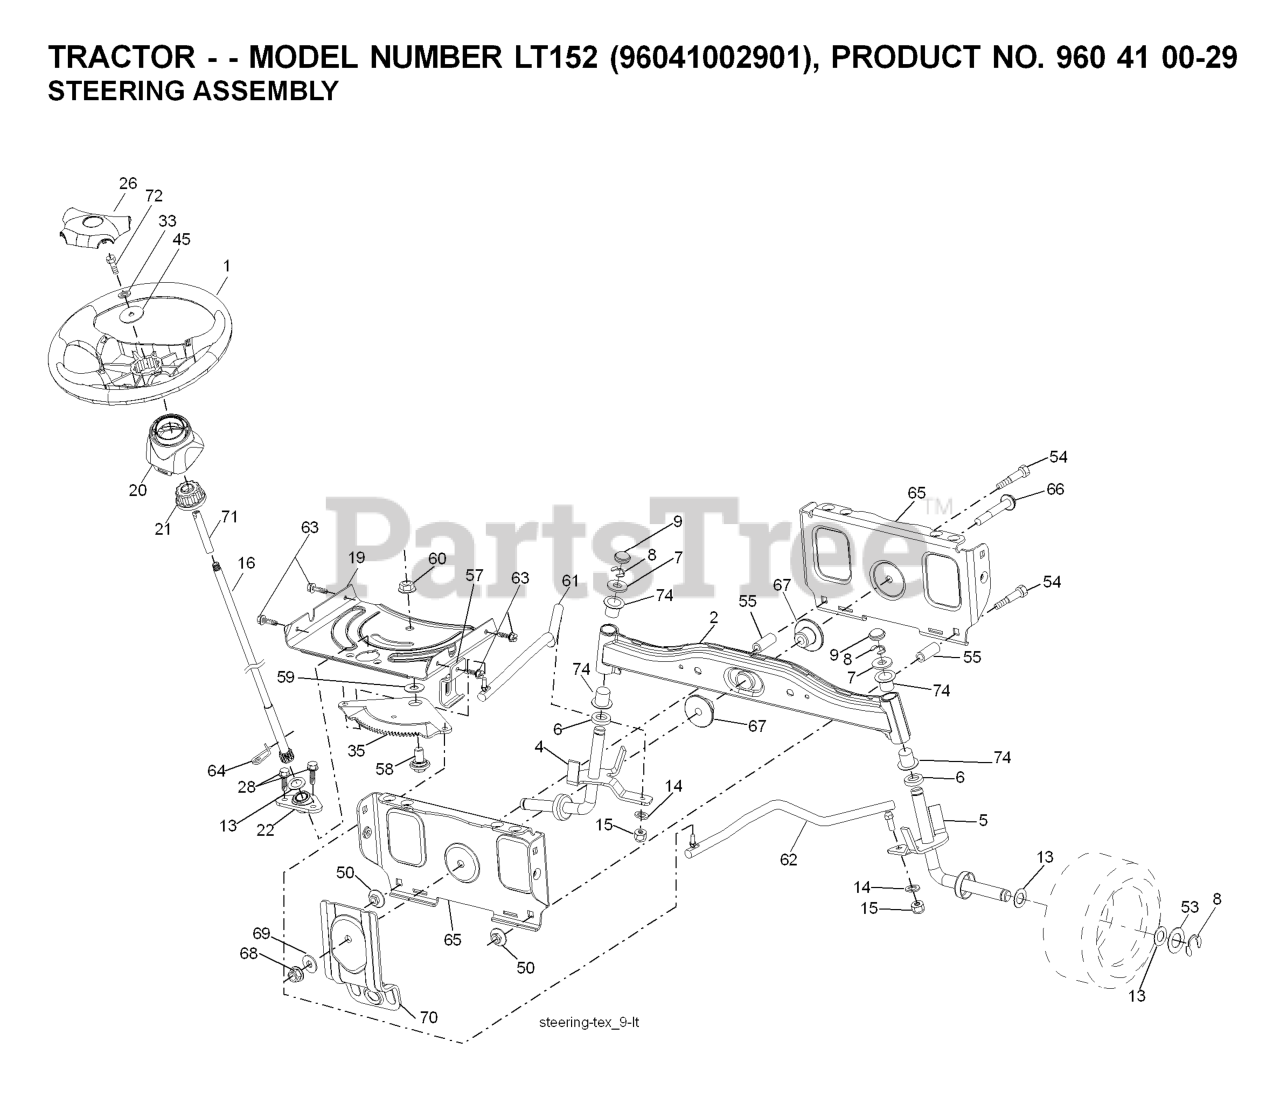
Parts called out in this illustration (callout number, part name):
1	WHEEL.STEERING.LEGEND2.GRY
2	AXLE.HALF.ASM.WELDED
4	SPINDLE.WELDED.LH.15"TEX
5	SPINDLE.WELDED.RH.15"T
6	THRUST WASHER
9	CAP.SPINDLE.BLACK
14	WASHER, LOCK 3/8
15	NUT CROWNLOCK 3/8-24
16	SHAFT STEERING
19	PLATE.STEER.DDL.NLT/NG
20	BOOT, STEERING
21	ADAPTER, WHEEL STNG..
22	BUSHING.ASM.STEERING.A
26	INSERT.CAP.STRG.WH.GRAY
28	SCREW, 3/8-16X3/4
33	WASHER.LOCK.HVY.HLCL.SPR.5/16
35	GEAR.SECTOR.PLATE.DDL.
45	WASHER.11/32
50	NUT LOCK FLG 3/8-16 UNC
53	WASHER.HARDENED
55	SPACER.BRACE.AXLE (2 2)
57	BRACKET.UPSTOP.TEX
58	BOLT.SHOULDER.SECTOR.P
59	WASHER.THURST.SECTOR.S
60	NUT FLANGE LOCK 5/8-11
61	DRAGLINK.LH.BALLSTUD.D
62	DRAGLINK.RH.BALLSTUD.D
63	SCREW
64	RETAINER.CLIP.SPRING.S
65	BRACE.AXLE.FRONT.NLT/N
66	BOLT HEX FGHD 7/16-14 X 3 SERR
67	BUSHING.PM.FRONT AXLE
68	NUT.LOCK.FLANGE.7/16
69	WASHER.1.5X.505X.118
70	BRKT.DECK.SUSPENSION.F
71	SHAFT EXTENSION STEERING
72	BOLT YT
74	BRNG T
